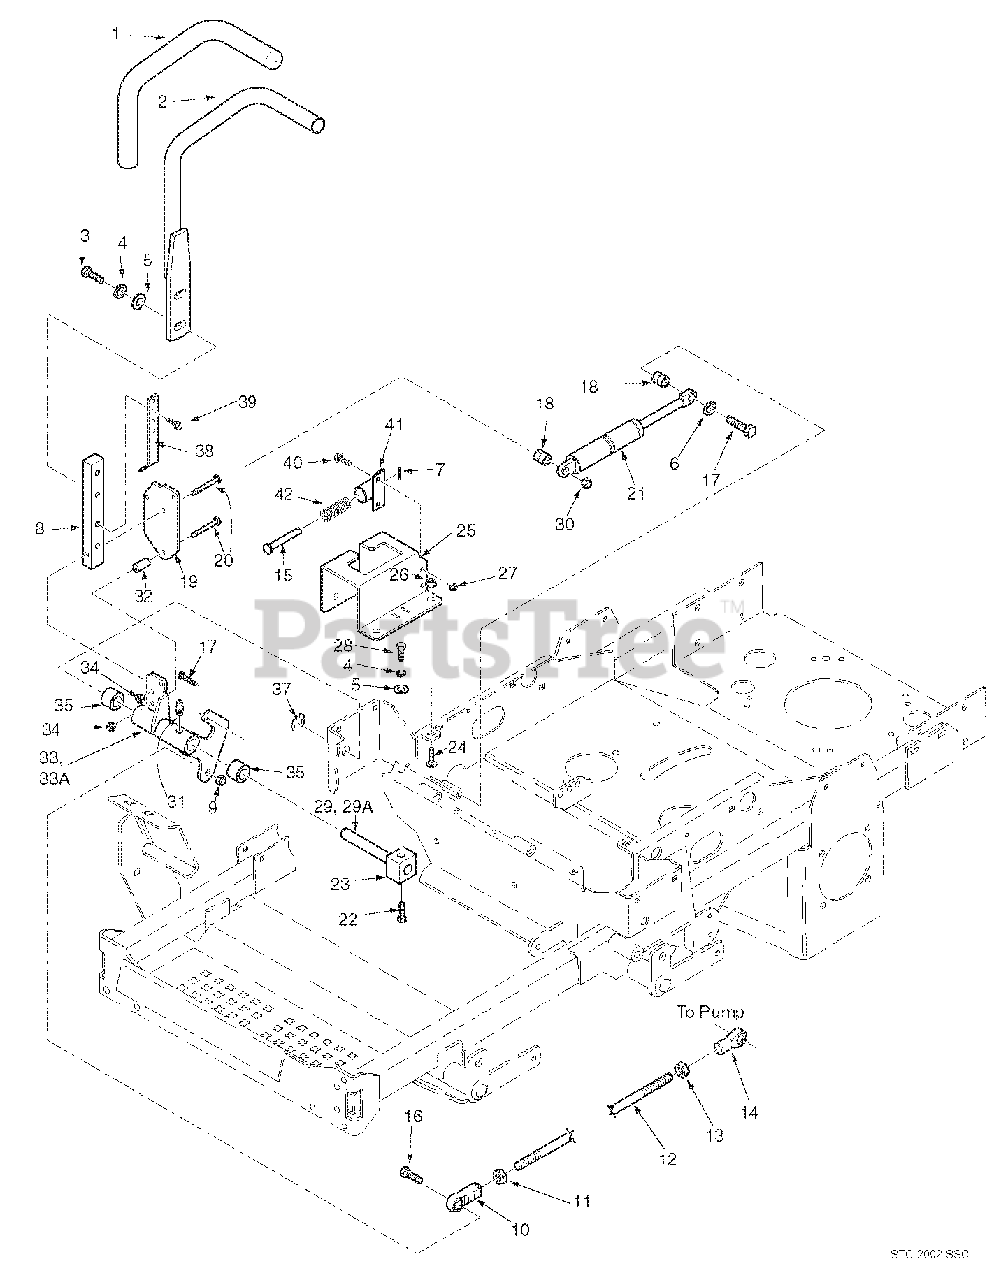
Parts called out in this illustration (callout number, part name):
1	Grip, Control Lever
2	Handle Bar
3	Bolt, Hex Head 3/8-16 x 1-1/4"
4	Lockwasher, 3/8"
5	Flatwasher, 3/8-.391 x .938 x .105"
6	Flatwasher, 5/16-.375 x .875 x .083"
7	Roll Pin, Spring 5/32 x 3/4"
8	Bar, Control Lever
9	Nut, Elastic Stop 3/8-16
10	Rod End, 3/8-24 RH Female
11	Nut, 3/8-24 RH Thread
12	Rod, Pump Control Linkage
13	Nut, 3/8-24 UNF-2B LH Thread
14	Rod End, 3/8-24 LH Thread
15	Pin Retainer
16	Bolt, Hex Head 3/8-16 x 1-1/2"
17	Bolt, Hex Head 5/16-18 x 1-3/4"
18	Spacer, Pump Dampener
19	Plate, Control Lever
20	Bolt, Hex Head 5/16-18 x 2"
21	Gas Damper
22	Bolt, Hex Head 3/8-16 x 1"
23	Block, Clamping
24	Bolt, Carriage, 5/16-18 x 3/4"
25	Control Plate - LH
26	Nut, Serr., Flange, 5/16-18
27	Nut, Elastic Stop 1/4-20
28	Bolt, Hex Head 3/8-16 x 3/4"
29	Shaft, Steering Control
30	Nut, Elastic Stop 5/16-18
31	Grease Fitting, 1/4-28 Self Tap
32	Spacer, Control
33	Control Lever Assy RH
34	Nut, Elastic Stop 5/16-18
35	Bushing
36	Flatwasher, 1-1/4 x 49/64 x 16 Ga.
37	Retaining Ring, 3/4" Ext.
38	Bracket, Switch Actuator
39	Bolt, Hex Serr. Flange 5/16-18 x 3/4"
40	Bolt, Carr. 1/4-20 x 3/4"
41	Bracket, Control Return
42	Spring
43	Pin Retainer
